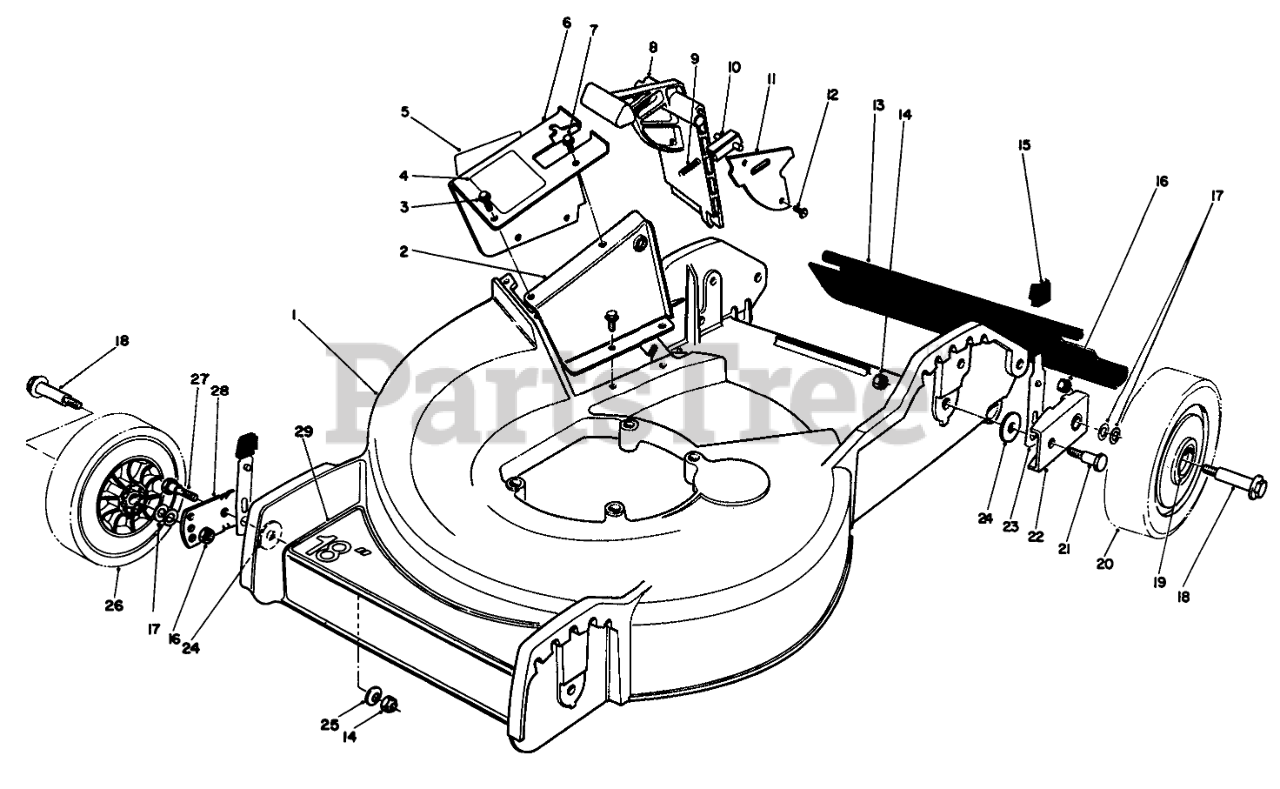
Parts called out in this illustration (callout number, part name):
1	HSG & CARTON
2	Tunnel-Inner
3	SCREW
4	DECAL - DANGER
5	DECAL-DANGER
6	Tunnel-Outer (Incl. Ref. #4 & 5)
7	SCREW
8	Door-Mulching
9	SPRING-COMPRESSION, LATCH
10	Door Latch
11	DOOR COVER
13	SHIELD - TRAILING
14	NUT-LOCK, NI
15	KNOB-ARM
16	Nut
17	WASHER
18	BOLT-WHEEL
19	BUSHING
20	Wheel & Tire Assembly (Incl. Ref. #19)
21	PIVOT SCREW
22	PIVOT ARM ASM
23	SPRING ARM ASM
24	PIVOT WASHER
25	WASHER-BELLEVILLE
26	Wheel & Tire Assembly (Incl. Ref. #19)
27	5/16-18 PIVOT SCREW
28	PIVOT ARM ASSY
29	DECAL - DECK
